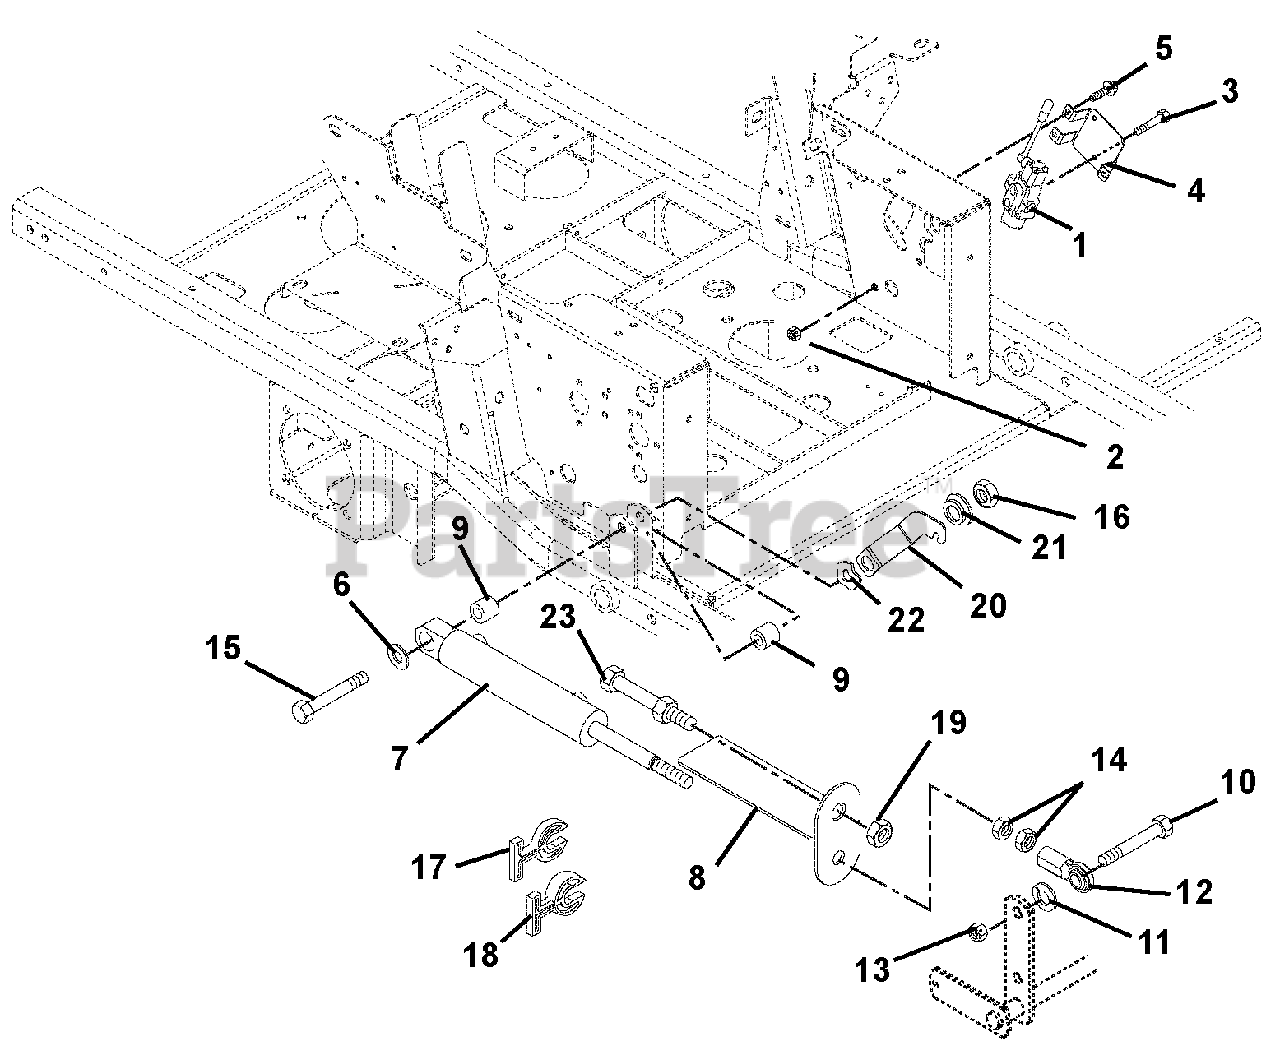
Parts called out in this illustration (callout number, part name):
1	Valve, Hydraulic
2	Nut, Locking Top Flange .31-18
3	Bolt, Hex .31-18 x 2.5 Grade 5
4	Bracket, Valve Mounting
5	Screw, Tapping .38-16 x .50 Hex Washer Head
6	Washer, Flat Steel .515 x 1.625 x .25
7	Cylinder, Hydraulic Lift
8	Strap, Cut Indicator / Guard
9	Bushing .516 x 1.00 x 1.05
10	Bolt, Hex .62-11 x 2.25 Grade 8
11	Washer, Lock .62 x .156
12	Rod End, Right Hand Female .625
13	Nut, Locking Center .62-11
14	Nut, Jam .625-18
15	Bolt, Hex .50-13 x 3.75 Grade 5
16	Nut, Locking Top Flange .50-13
17	Stop, Cylinder .34 Thick
18	Stop, Cylinder .68 Thick
19	Nut, Jam .75-16
20	Latch, Footboard
21	Bushing, Flange .515 x .75 x .275 x 1.12
22	Washer, Wave .076 x 1.12 x .08
